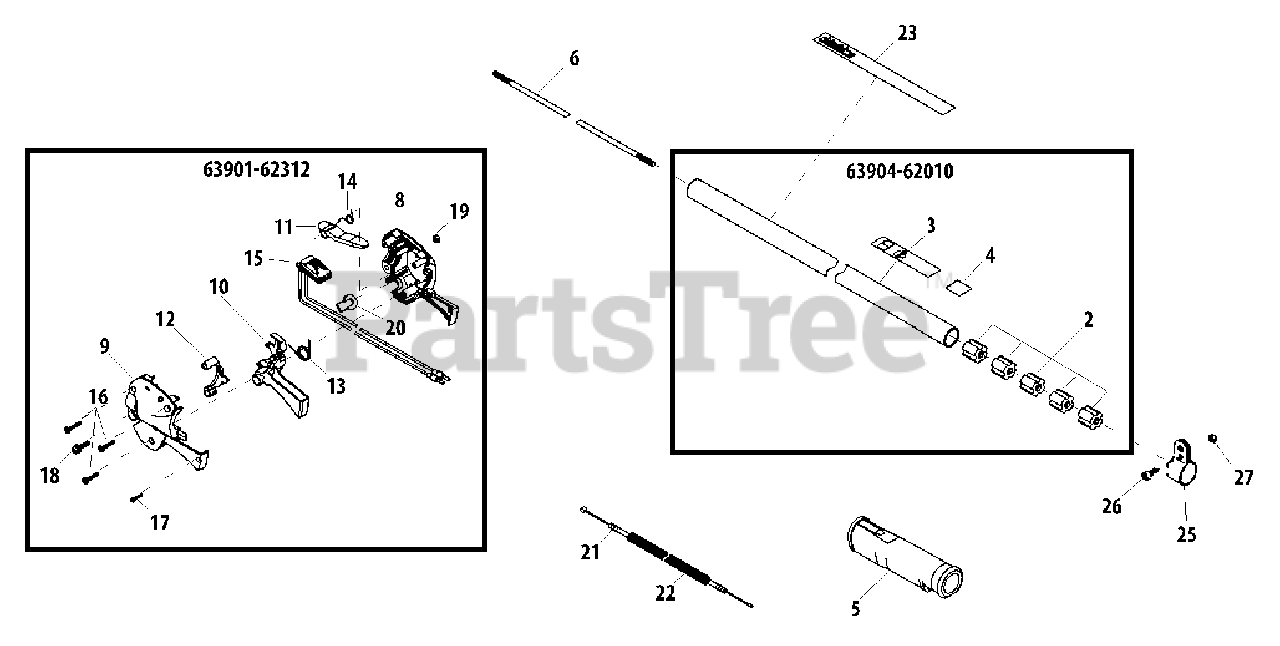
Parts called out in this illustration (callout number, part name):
2	BUSHING
3	LABEL - CAUTION
4	LABEL - INSTRUCTION
5	GRIP
6	PIPE, MAIN
8	HANDLE, CONTROL - RIGHT
9	HANDLE, CONTROL - LEFT
10	LEVER
11	LEVER, LOCK
12	HOLDER
13	SPRING
14	SPRING
15	SWITCH, IGNITION
16	SCREW - 4X20 -- TAPPING
17	SCREW - 3X14 -- TAPPING
18	SCREW - 5X20
19	NUT - 5
20	PLUG
21	CABLE, THROTTLE
22	TUBE
23	LABEL - TRADE
25	BRACKET
26	SCREW - 5X12
63901-62312	THROTTLE LEVER ASSY
63904-62010	MAIN PIPE ASSY
